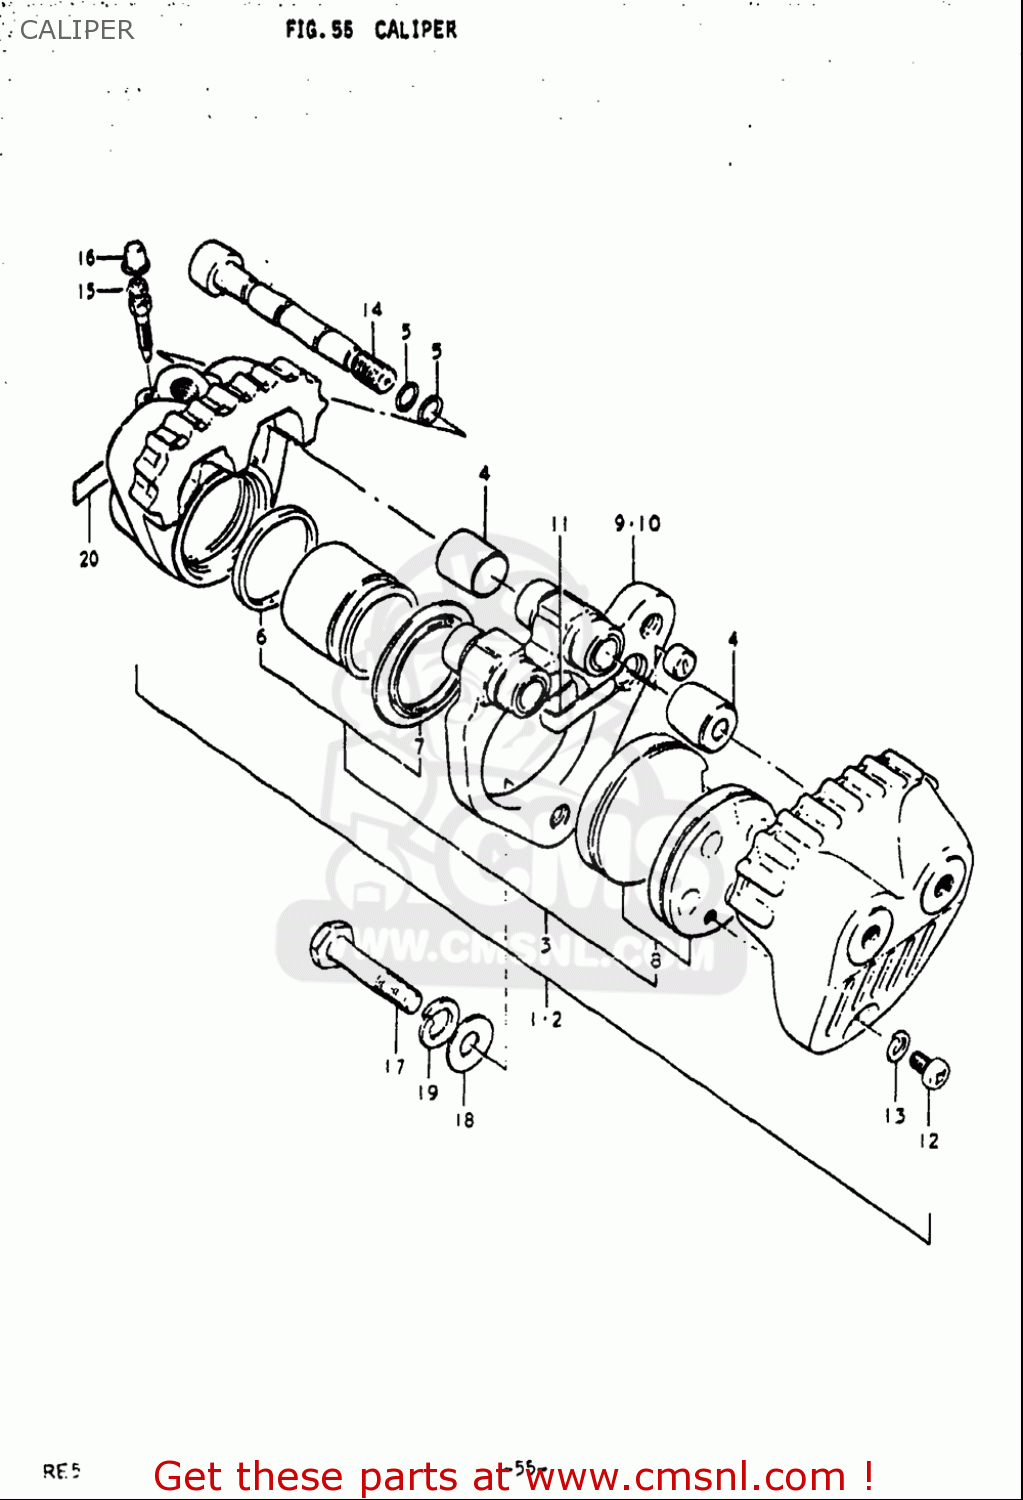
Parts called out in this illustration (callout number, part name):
3	PISTON SET
4	COVER,AXLE DUST
5	O RING,CALIPER AXLE
6	SEAL,PISTON
7	BOOT,PISTON
8	PAD SET (NAS)
12	SCREW
13	WASHER,LOCK
14	AXLE,CALIPER
15	BLEEDER
16	CAP,BLEEDER PLUG
17	BOLT(10X38)
18	WASHER
19	WASHER,LOCK
